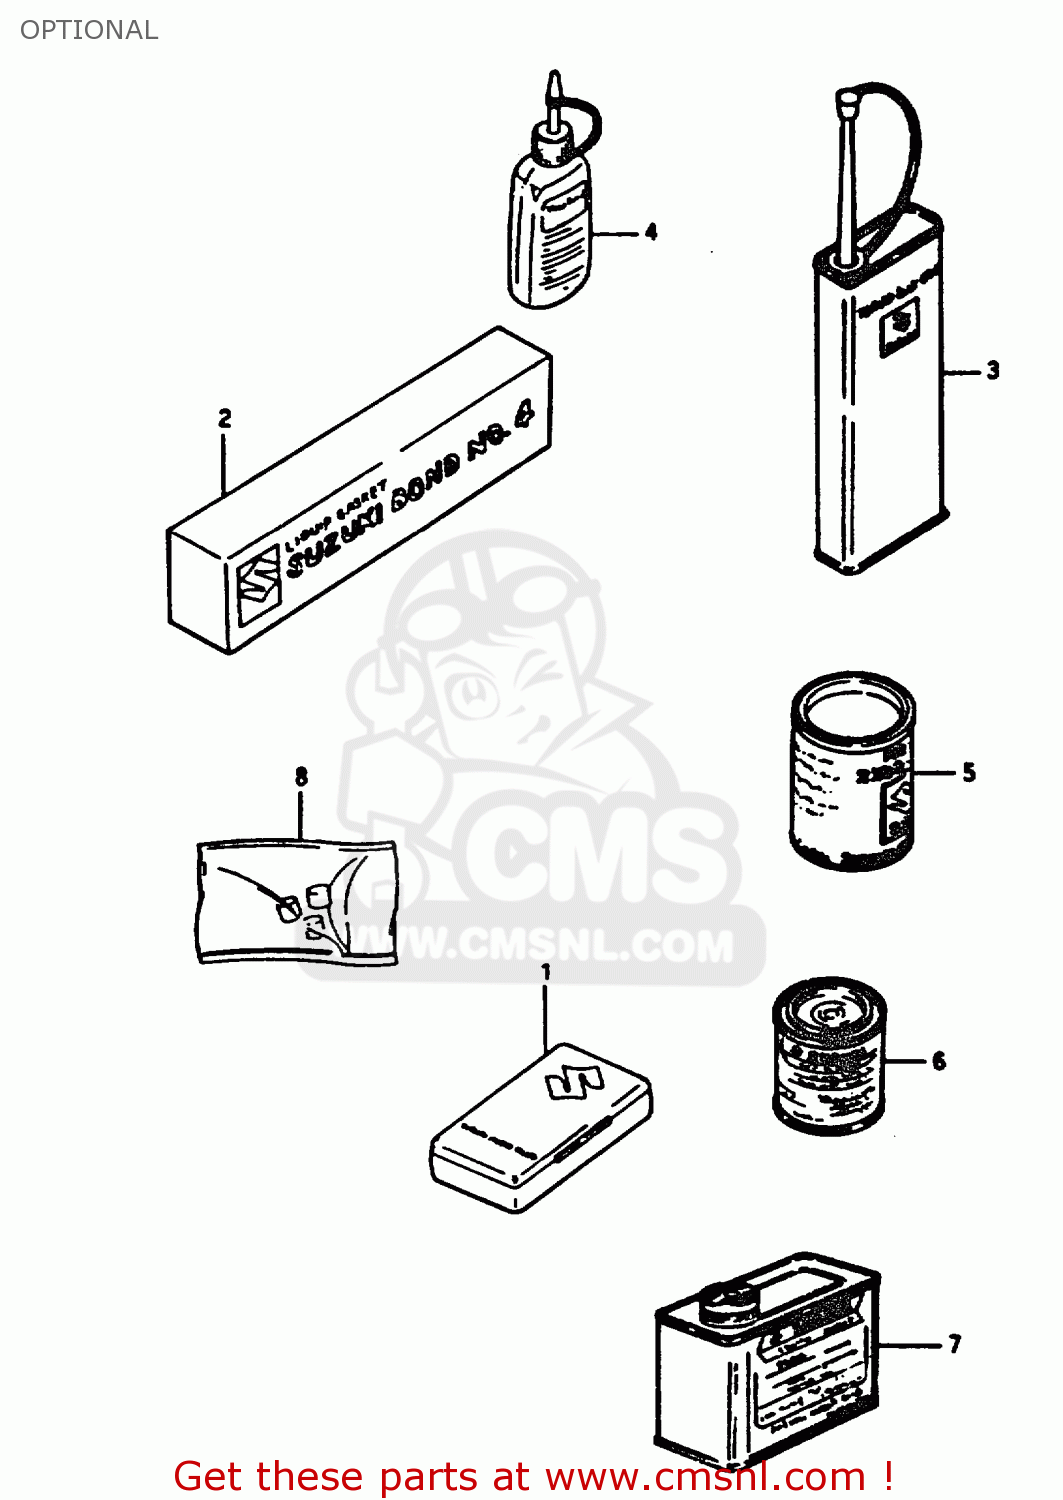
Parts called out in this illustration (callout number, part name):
1	TUBE REPARING TOOL
2	BOND 1104
3	THREAD LOCK NO.1401 CLEAR 200G
4	THREAD LOCK NO
5	GREASE(C)EP2 LITHIUM 150G
6	PAINT,BLACK
7	PAINT (MEDIUM GOLD)
8	ANTI-LEAK ADDITIVE
